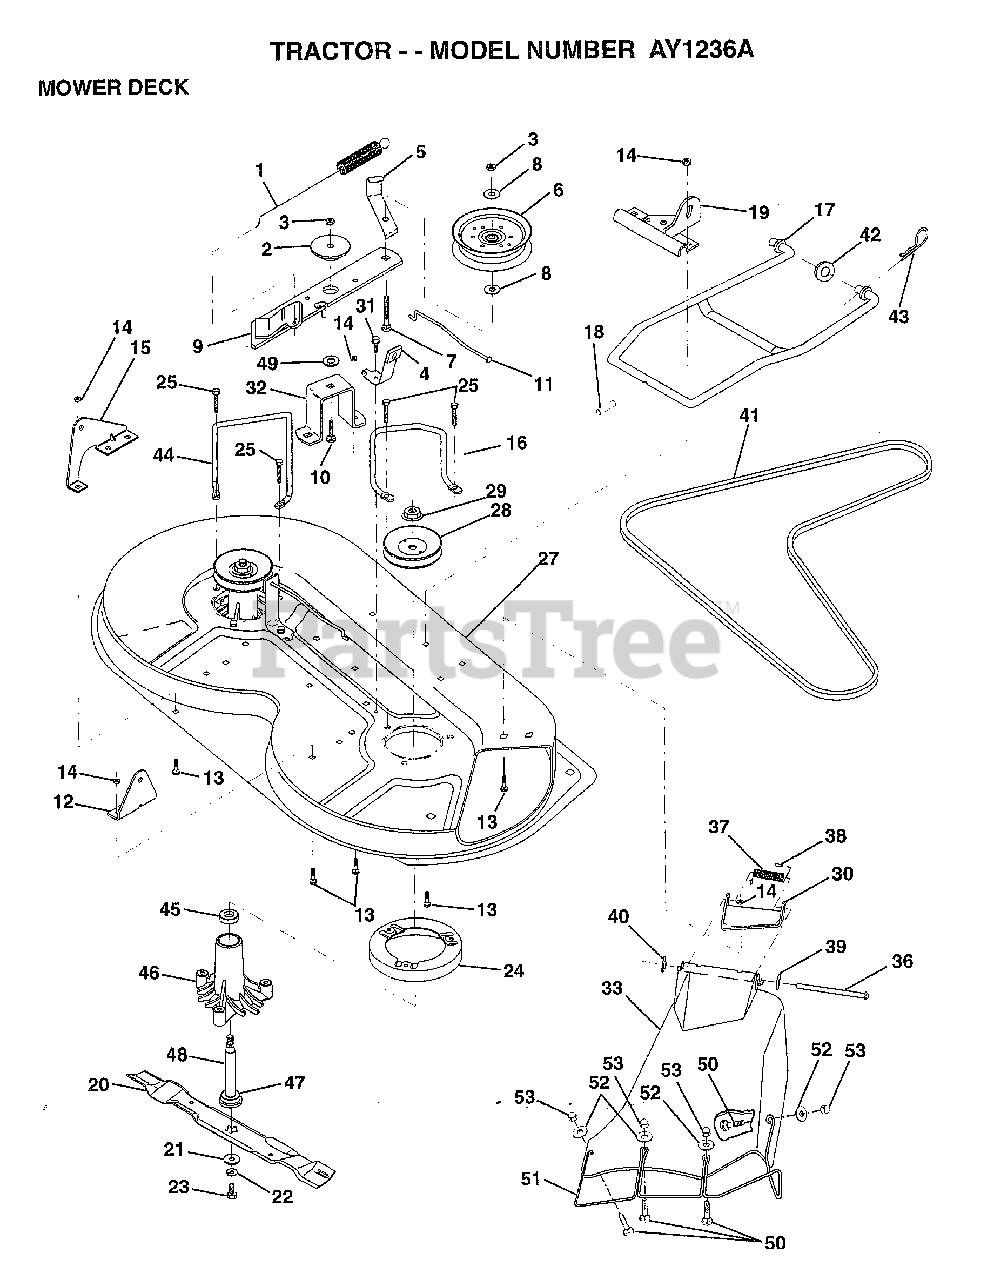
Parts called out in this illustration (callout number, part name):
1	SPRING CLUTCH MWR
2	SPACER RETAINER
4	BRAKE ASM
5	IDLER BELT GUIDE
6	PULLEY IDLER
7	BOLT
8	WASHER
10	BOLT.3/8-14X1.25
11	BRAKE ROD
12	"BRKT,LIFT REAR"
13	BOLT
15	"BRKT,LIFT REAR LH"
16	"KEEPER-BELT,RH"
17	MOWER LINK STAB
18	"PIN,GROOVE"
19	"BRKT,LINK STABILI"
20	"BLADE.36"" HIPERF"
21	WASHER.HARD.BLADE
23	BLADE BOLT
24	STRIPPER RND MWR
28	PULLEY.MANDREL.42
31	SCREW LT
32	"SUPT,IDLER ARM"
33	SHIELD.DEFL.36TUV
36	HINGE ROD
37	SPRING TORSION
38	CAP-SLEEVE LT
39	WASHER
40	NUT PUSH M
41	V-BELT.PRIM.78.5.
43	RETAINER.SPRING
44	KEEPER BELT LH
45	BEARING
46	HSG ASM MANDREL
47	BEARING.BALL
49	HARDENED WASHER
50	SCREW
51	GUARD.DFTR.MWR.36
53	ACORN NUT RB
